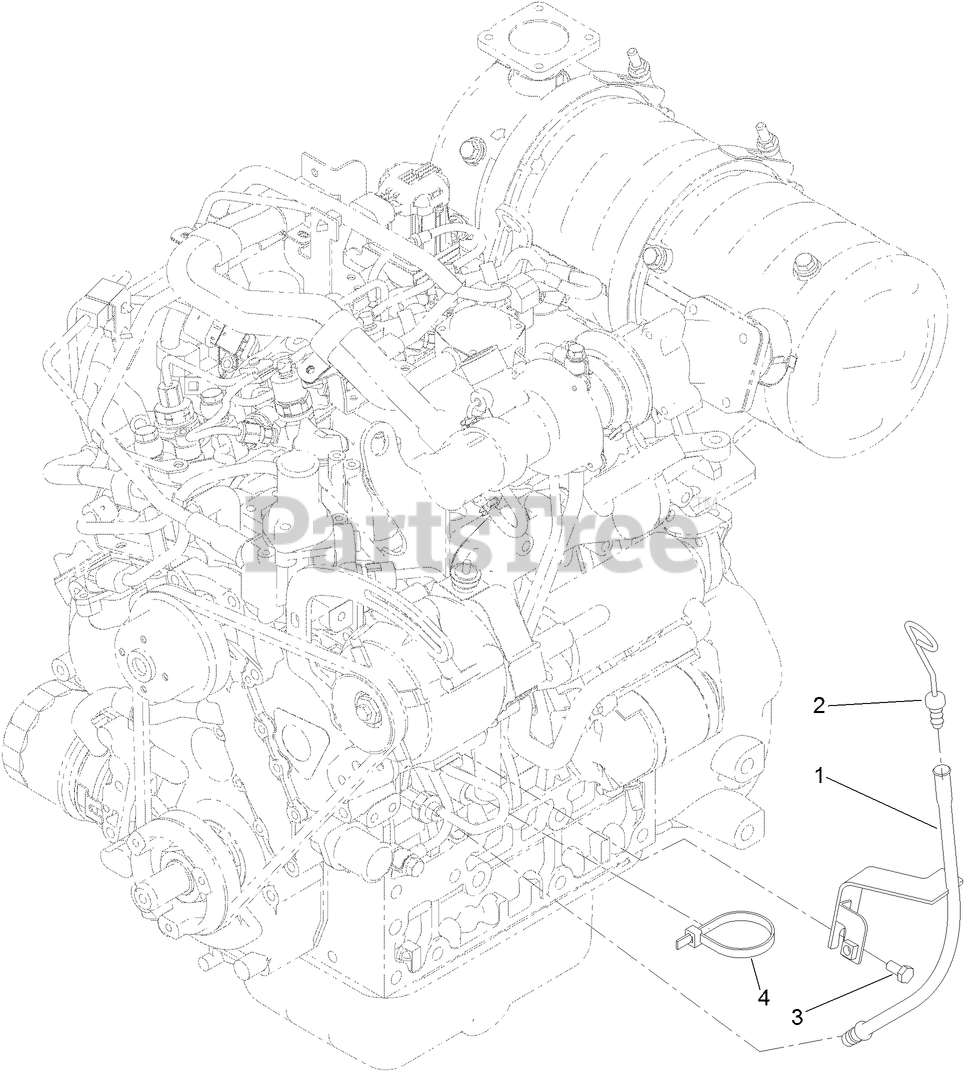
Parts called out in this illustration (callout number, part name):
1	GUIDE-DIPSTICK
2	DIPSTICK
3	BOLT-FLANGE
4	TIE-CABLE
